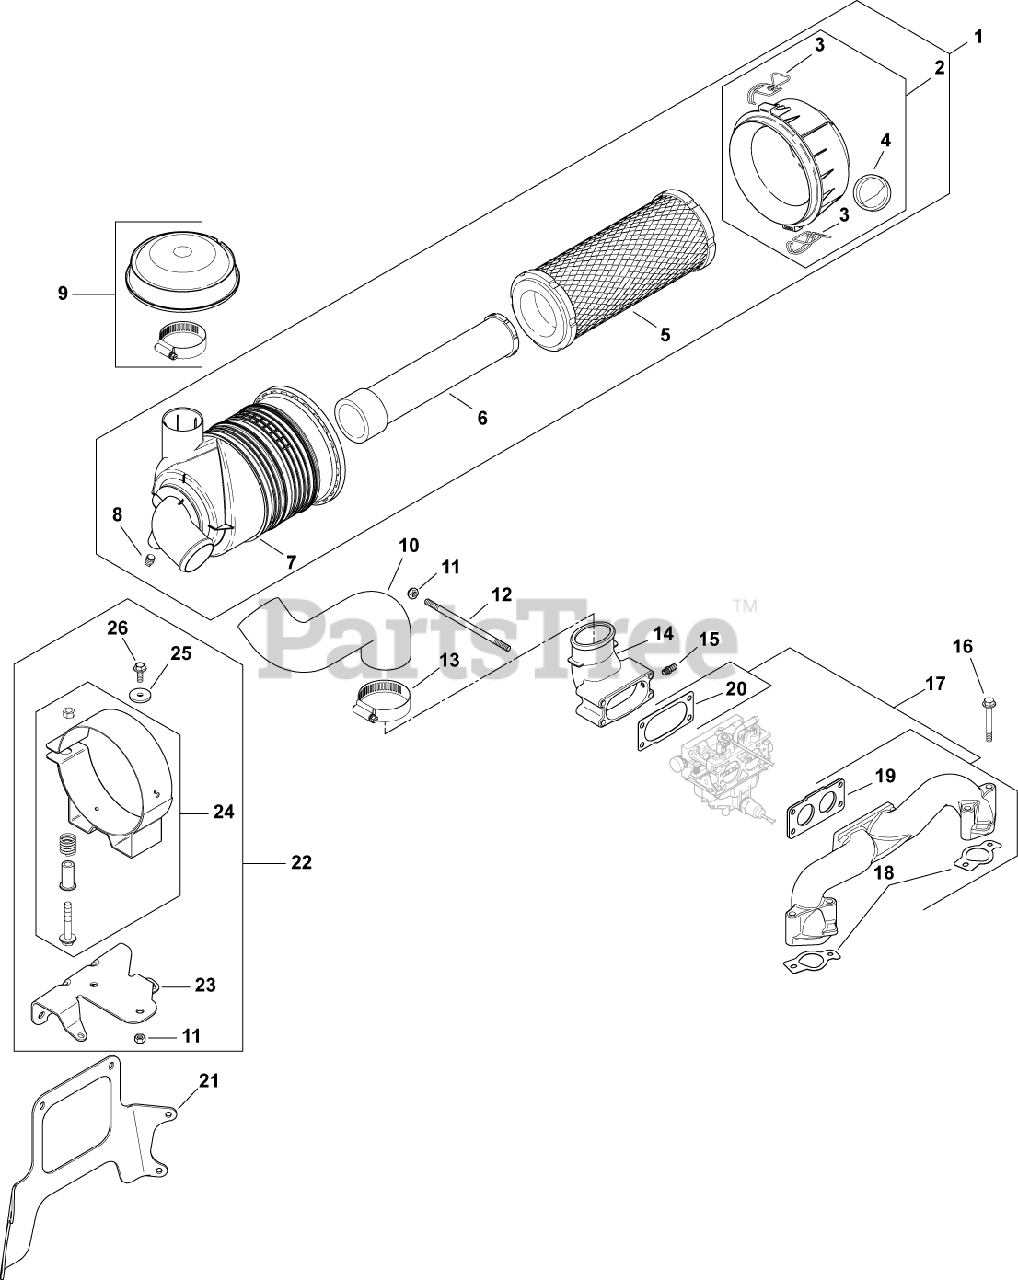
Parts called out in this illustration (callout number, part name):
1	AIR CLNR, CANISTER-USE 25 048 17-S
2	COVER ASSEMBLY, AIR CLEANER
3	CLIP - USE 62 154 07-S
4	VALVE, DUST EJECTOR
5	ELEMENT, AIR FILTER - PRIMARY
6	ELEMENT, AIR FILTER - SAFETY
7	HOUSING, HD AIR CLEANER
8	PLUG, PIPE
9	HOOD, AIR CLEANER (5.25)-USE 25 324 04-S
10	HOSE, AIR CLEANER
11	NUT, LOCK M6X1.0
12	STUD,M6X1.0X122
13	CLAMP, HOSE
14	KIT, A/C ELBOW-USE 24 054 39-S
15	FITTING, BARBED - USE 25 294 16-S
16	SCREW, FLG M6X1.0X55
17	KIT, INTAKE MANIFOLD
18	GASKET, INTAKE MANIFOLD USE 24 041 79-S
19	GASKET, CARBURETOR - USE 24 041 82-S
20	GASKET,AIR CLEANER ELBOW-USE 24 041 63-S
21	BRACKET,MAIN SUPPORT - USE 24 126 227-S
22	BRACKET, AIR CLEANER -USE 24 126 186-S
23	BRACKET, AIR CLEANER-USE 24 126 184-S
24	BRACKET, AIR CLEANER-USE 24 126 191-S
25	WASHER, FLAT 1/4" (O.D. 1")
26	SCREW, FLG M6X1.0X16
